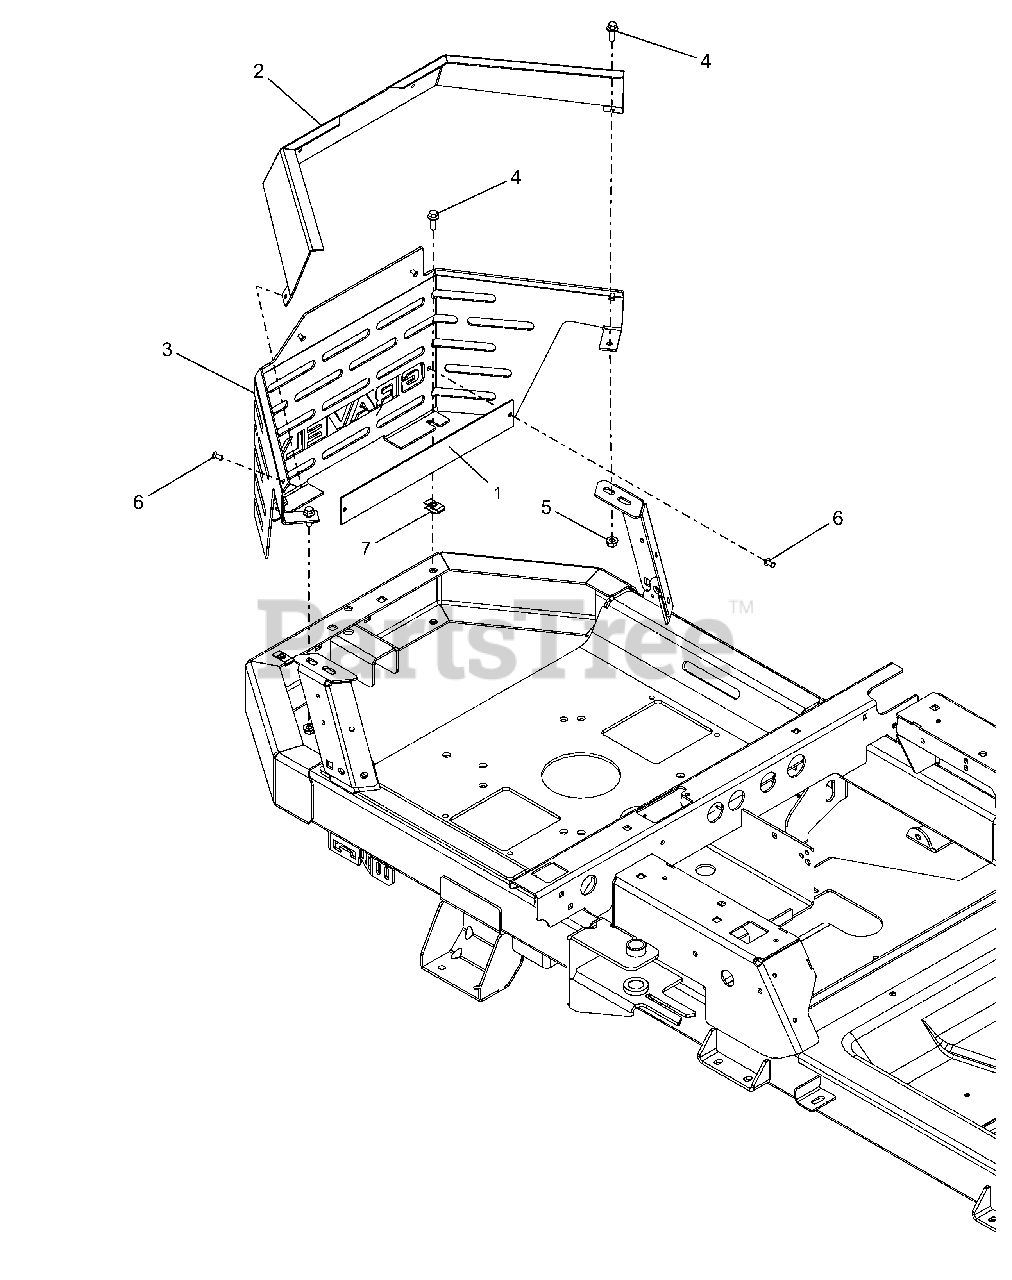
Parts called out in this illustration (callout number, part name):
1	PLATE, SHROUD BACKER
2	WLDMT, ENGINE SHROUD TRIM-XL
3	SHROUD, ENGINE - GRAVELY XL
4	BLT,HEX-FLG .25-20X.75 G5 BFP
5	@NUT-LK-TOP-FLG .25-20 YWZC
6	RIVET, #66 STEEL POP PD BLACK
7	NUT-RTNR .25-20X.56
